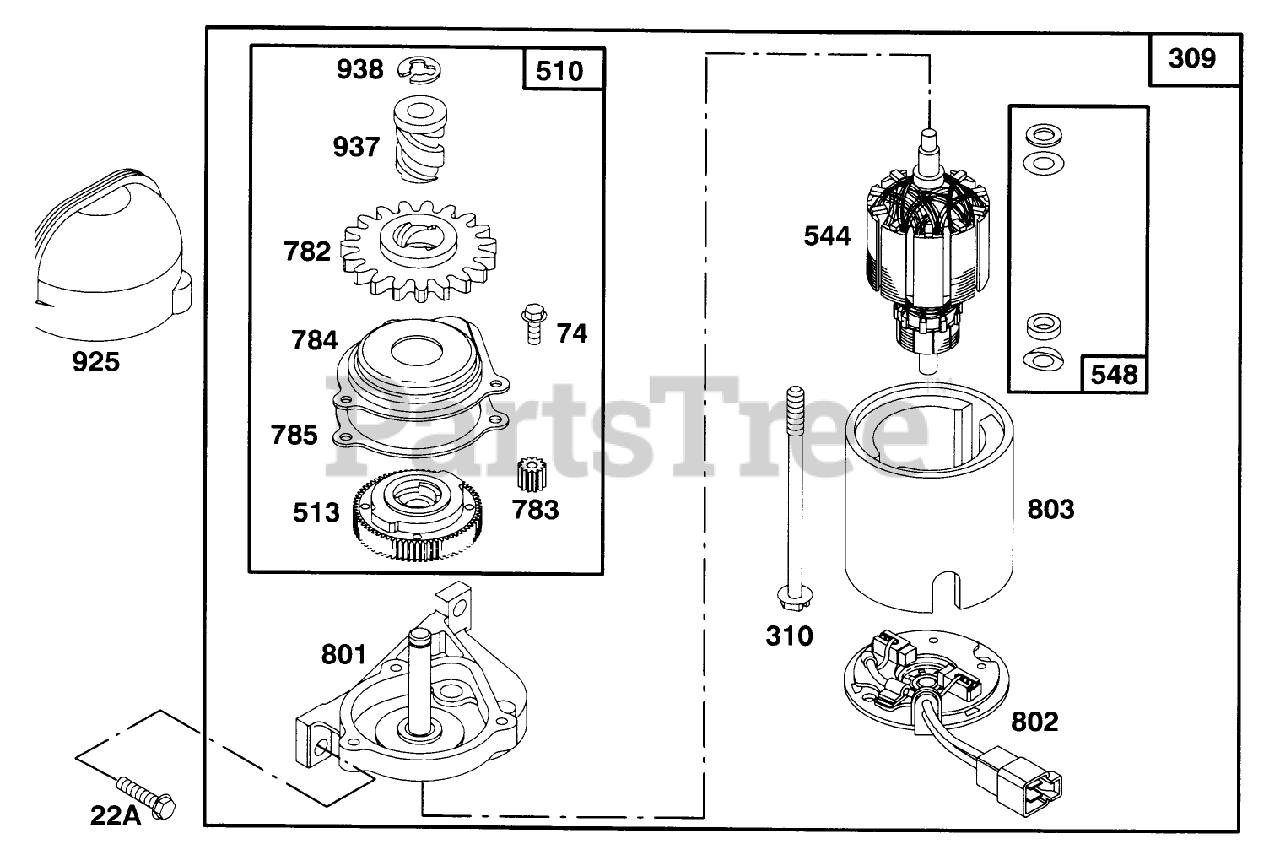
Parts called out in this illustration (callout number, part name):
22A	SCREW - CARBUERTOR MTG
510	DRIVE SET
513	CLUTCH - STARTER
548	WASHER ASSEMBLY
782	GEAR - STARTER
925	COVER - STARTER
938	RETAINER - LOCK
